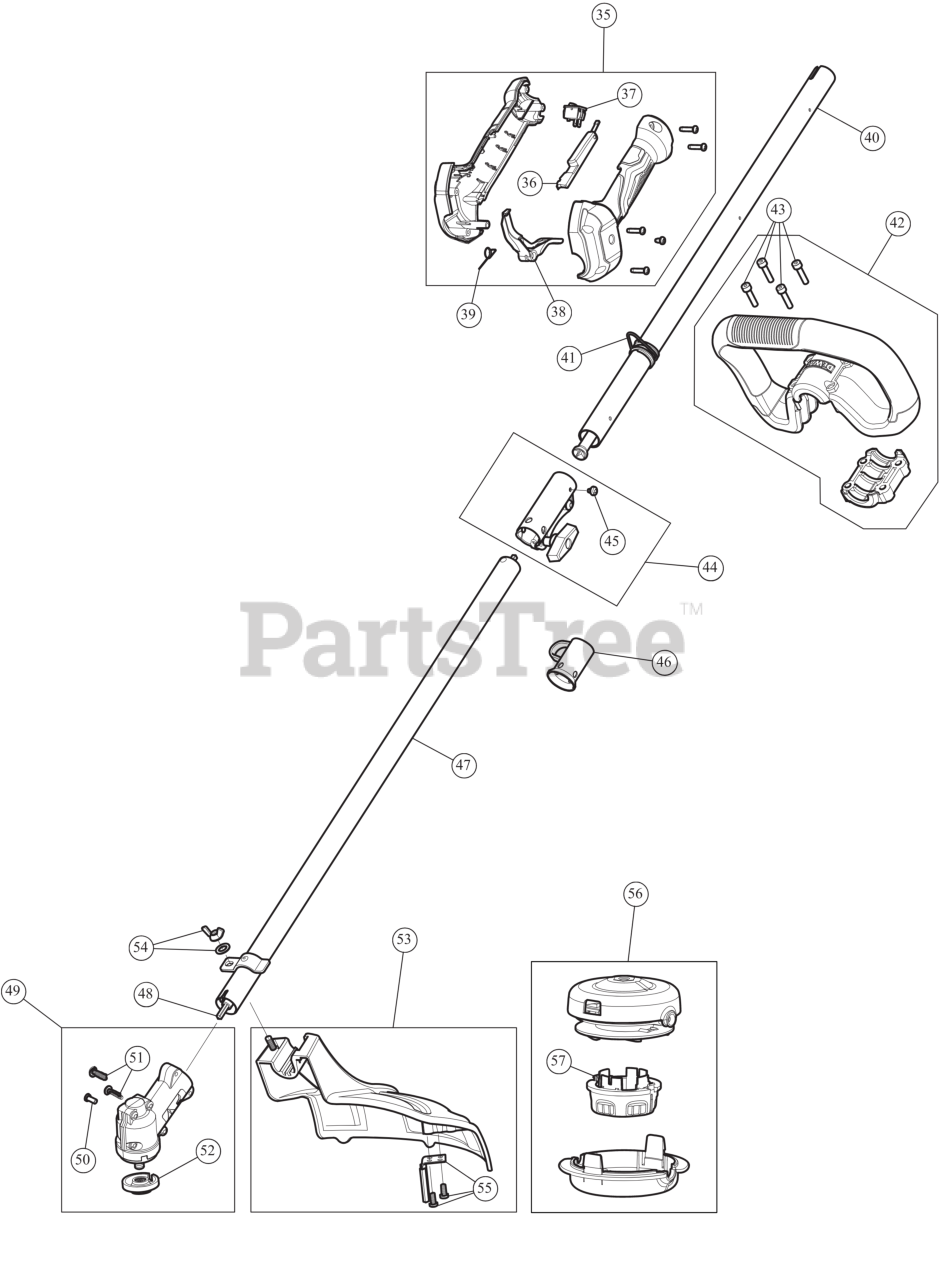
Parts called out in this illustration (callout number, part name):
35	THROTTLE GRIP
36	THROTTLE LOCK LEVER
37	SW, MOMENTARY ON/O
38	THROTTLE TRIGGER
39	SPRING TRIG
40	BOOM ASSEMBLY UPR
41	CLAMP-SHOULDER STR
42	HANDLE
43	HANDLE BOLT
44	SPLIT BOOM COUPLER KIT
45	SCREW, 10-32X.250 TA
46	HANGER
47	LOWER SHAFT HOUSING
48	LOWER DRIVE SHAFT
49	GEARBOX LCBC
50	SCREW, 8-32 x .312 P
51	SCREW #
52	CUTTING HEAD SPACER
53	GUARD
54	BLADE GUARD MOUNTING HARDWARE
55	BLADE ASSEMBLY W/HDW
56	CUTTING HEAD
57	BUMP KNOB
